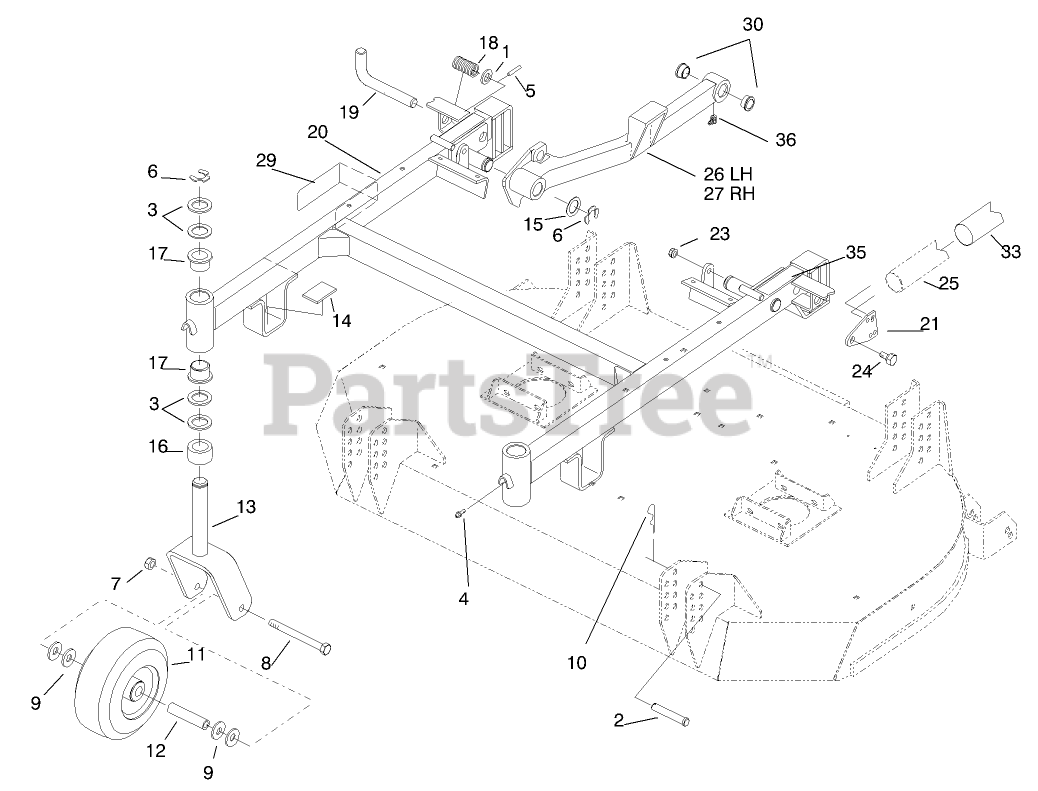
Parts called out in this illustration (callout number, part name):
1	WASHER
2	PIN-CLEVIS
3	WASHER-THRUST
4	FITTING-GREASE
5	PIN-ROLL
6	RING-RETAINING
7	NUT-HEX
8	SCREW-HH
9	WASHER-FLAT
10	PIN-HAIR
11	CASTOR WHEEL ASM
12	SPANNER-TIRE
13	Castor Fork
14	CUSHION - RUBBER
15	Washer
16	SPACER-CASTOR
17	BUSHING
18	SPRING-COMPRESSION
19	PIN - PIVOT
20	Frame-Carrier
21	PLATE-END, SPRING
23	NUT-LOCK, NI
24	BOLT-SHOULDER
25	SPRING-EXTENSION
26	Push Arm ASM LH
27	Push Arm ASM RH
29	DECAL - HOC
30	BEARING-FLANGE
33	COVER-SPRING
35	DECAL-WARNING
36	FITTING-GREASE
